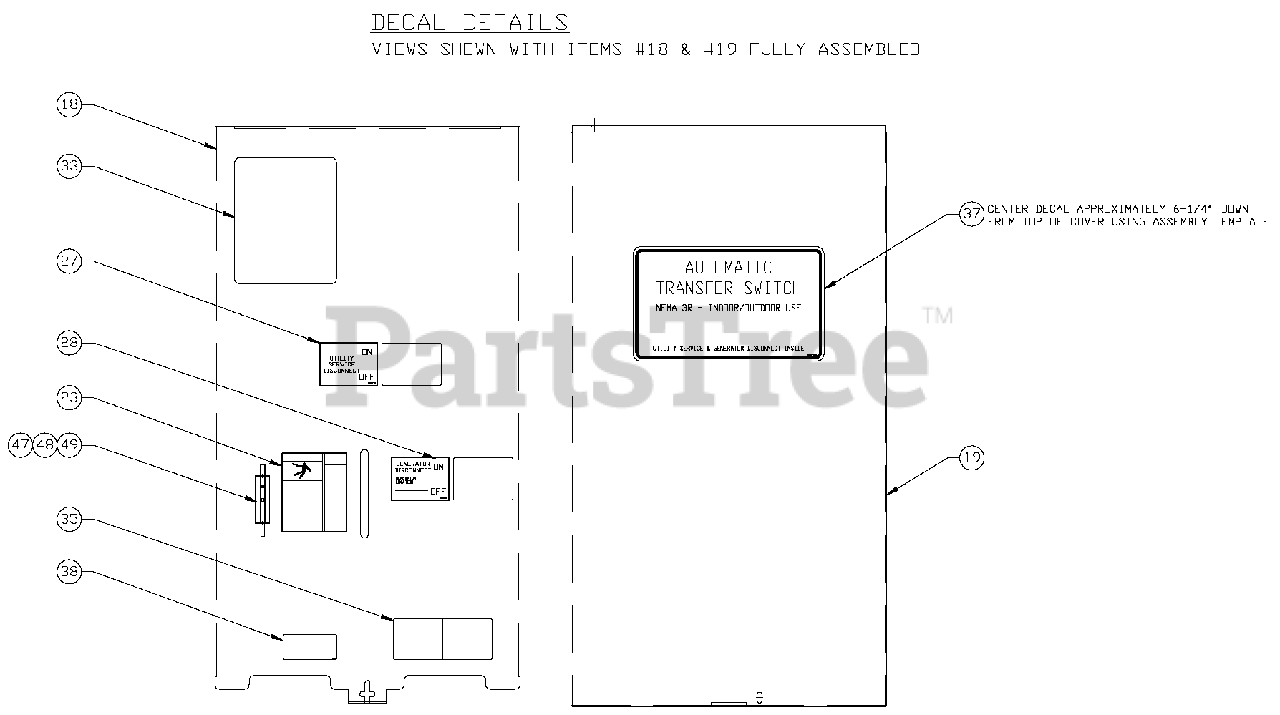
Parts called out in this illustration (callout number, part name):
18	COVER, INSIDE 200A DUAL BREAKER
19	COVER, TRANSFER SWITCH
23	DECAL, MANUAL OPERATING HANDLE
27	DECAL, UTILITY DISCONNECT
28	DECAL, GENERATOR DISCONNECT
33	DECAL, TEST SEQUENCE
35	DECAL, TERMINAL SHOCK HZD BI
37	DECAL, FRNT CVR ATS 3R SER DIS
38	DECAL LIVE CIRCUIT ENG/FRN/SPN
47	BRACKET, ARM EXTENDER
48	RIVET POP .156 X .362 AL
49	ARM EXTENDER PIN
